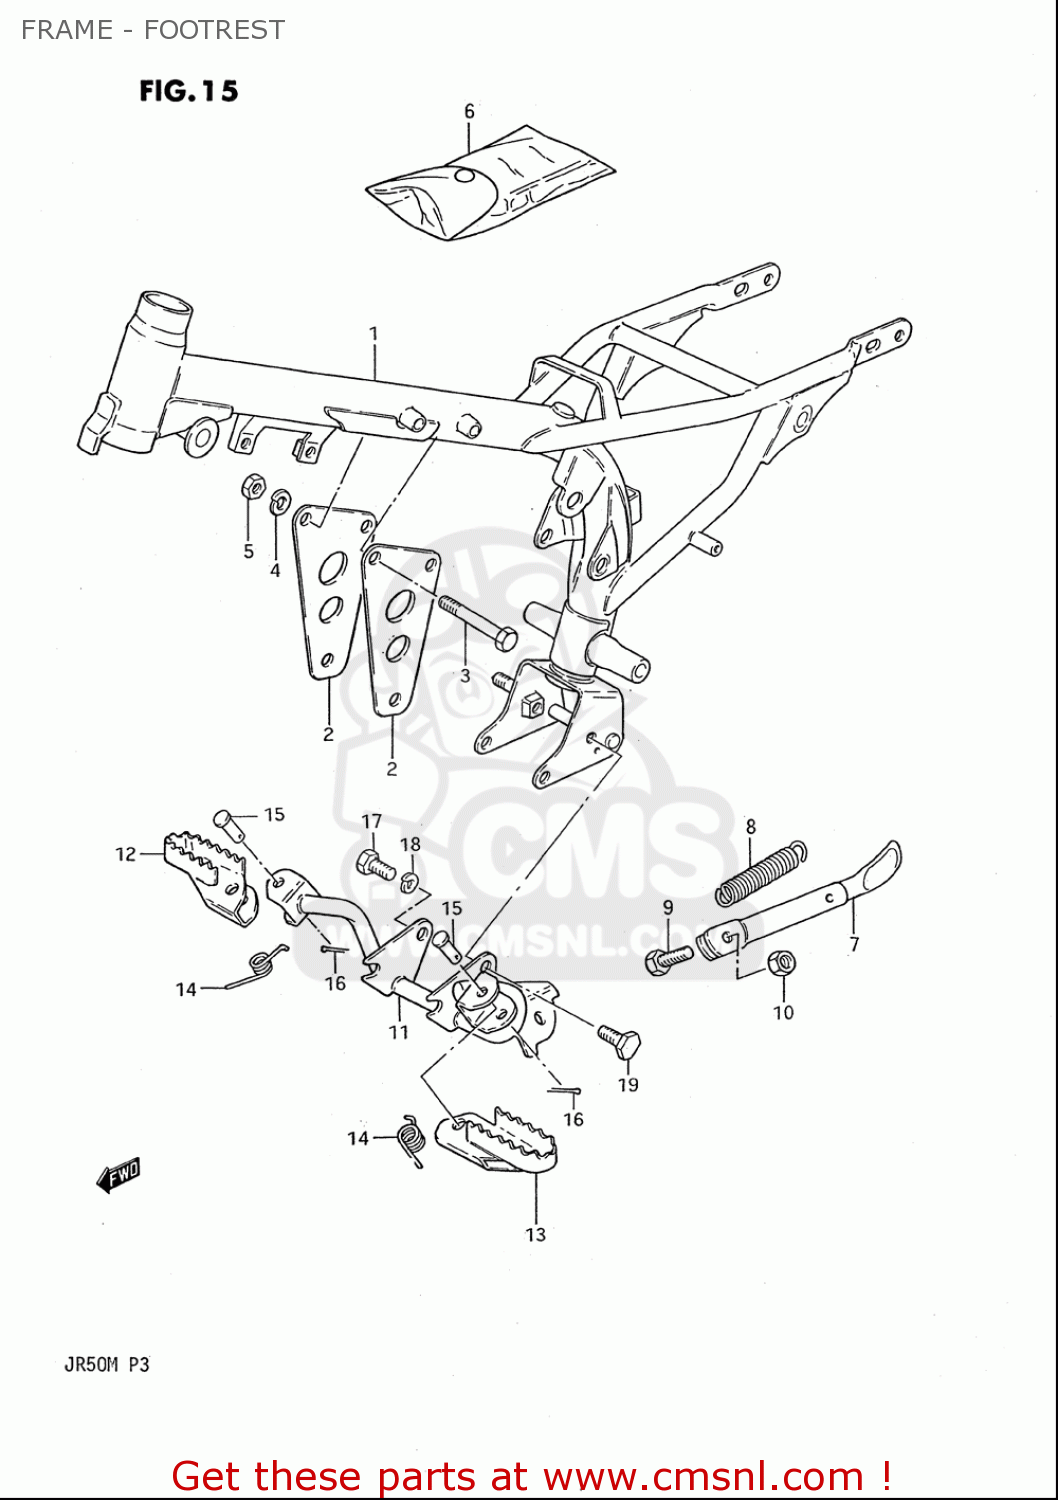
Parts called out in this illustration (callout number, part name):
2	PLATE,ENG MTG
3	BOLT
4	WASHER,LOCK
5	NUT
6	TOOL ASSY
7	STAND,PROP
8	SPRING
10	NUT
11	BAR,FR FOOTREST
12	FOOTREST,FRONT,RIGHT
13	FOOTREST,FRONT,LEFT
14	SPRING
15	PIN
16	PIN
17	BOLT
18	WASHER,LOCK
19	BOLT(8X14)
